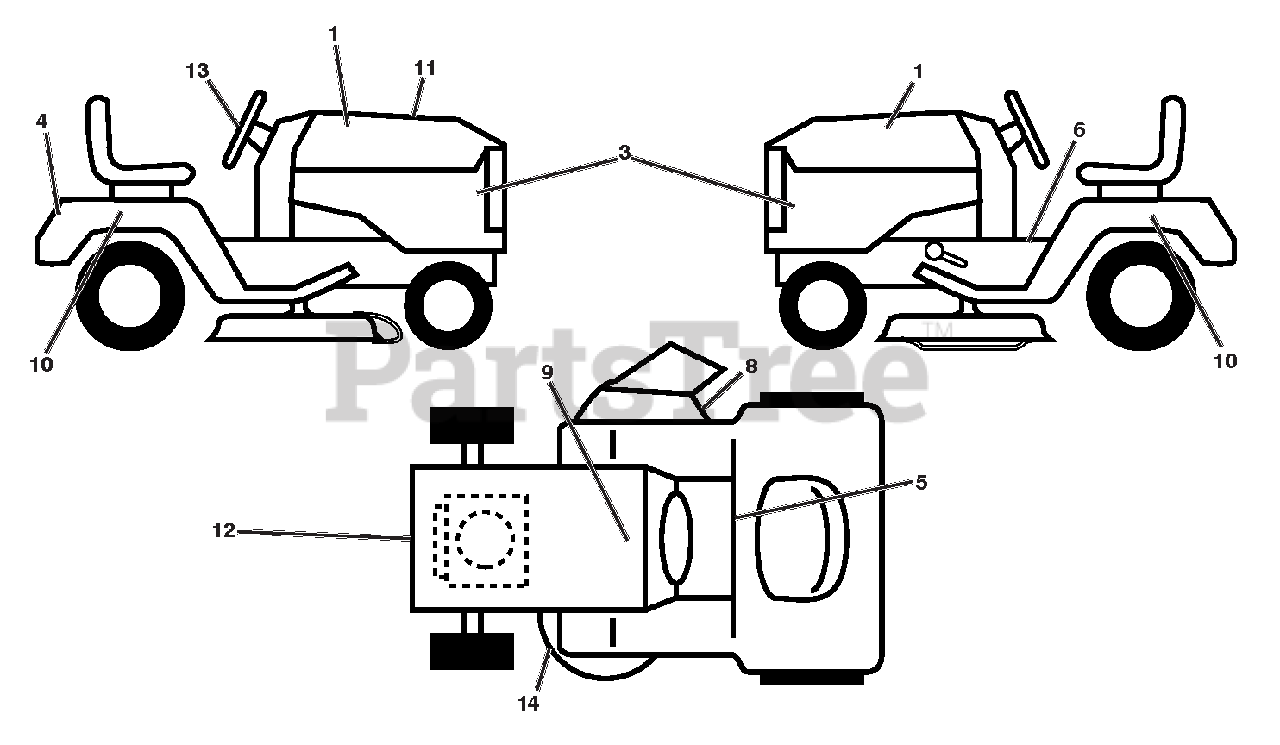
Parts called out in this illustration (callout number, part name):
1	DECAL.HOOD.RH.PRECISION.ARIENS
3	Decal, Side Panel
4	DECAL.FENDER.REAR.ARIENS
5	DECAL.FENDER
6	DECAL, WARNING START INST.
8	DECAL.MOWER.WARN.KEEP HAND AWY
9	DECAL.BAT.DAN/POI P/L SYM.WPN
10	DECAL.FENDER.SIDE.HYDRO.ARIENS
11	DECAL REPLACEMENT
12	DECAL ENGINE
13	DECAL.WHEEL.STEER.ARIENS
14	DECAL.V-BELT.SCH.42/46"MEC/ELE
